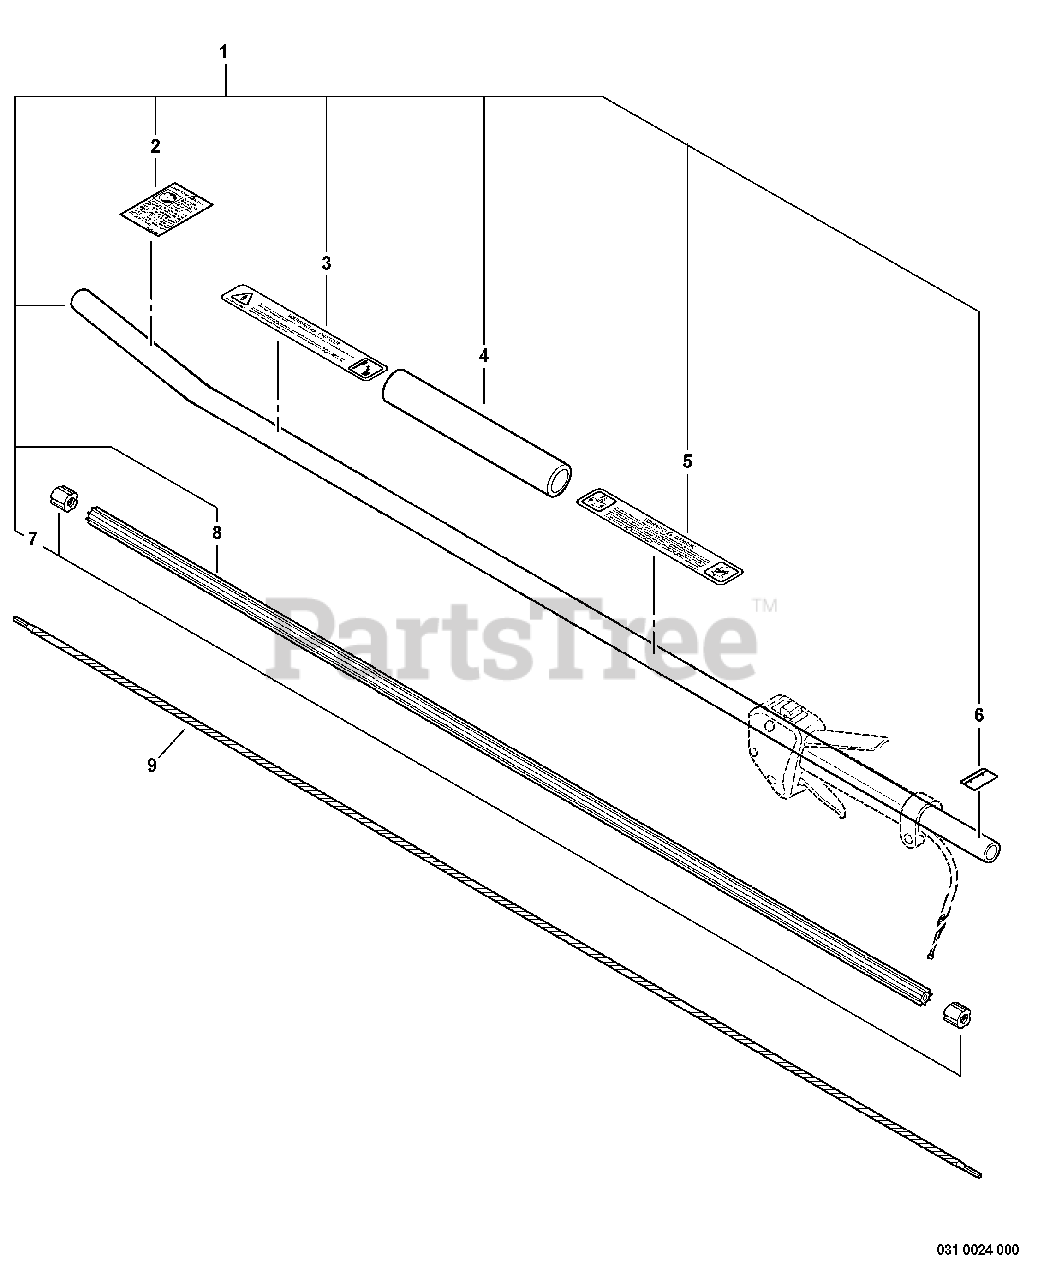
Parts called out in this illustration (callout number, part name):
1	MAIN PIPE ASSY
2	LABEL - CAUTION -- SPANISH
3	LABEL - CAUTION
4	GRIP, HANDLE
5	LABEL - CAUTION
6	LABEL - ALIGNMENT
8	LINER - FLEXIBLE
9	DRIVESHAFT - FLEXIBLE
